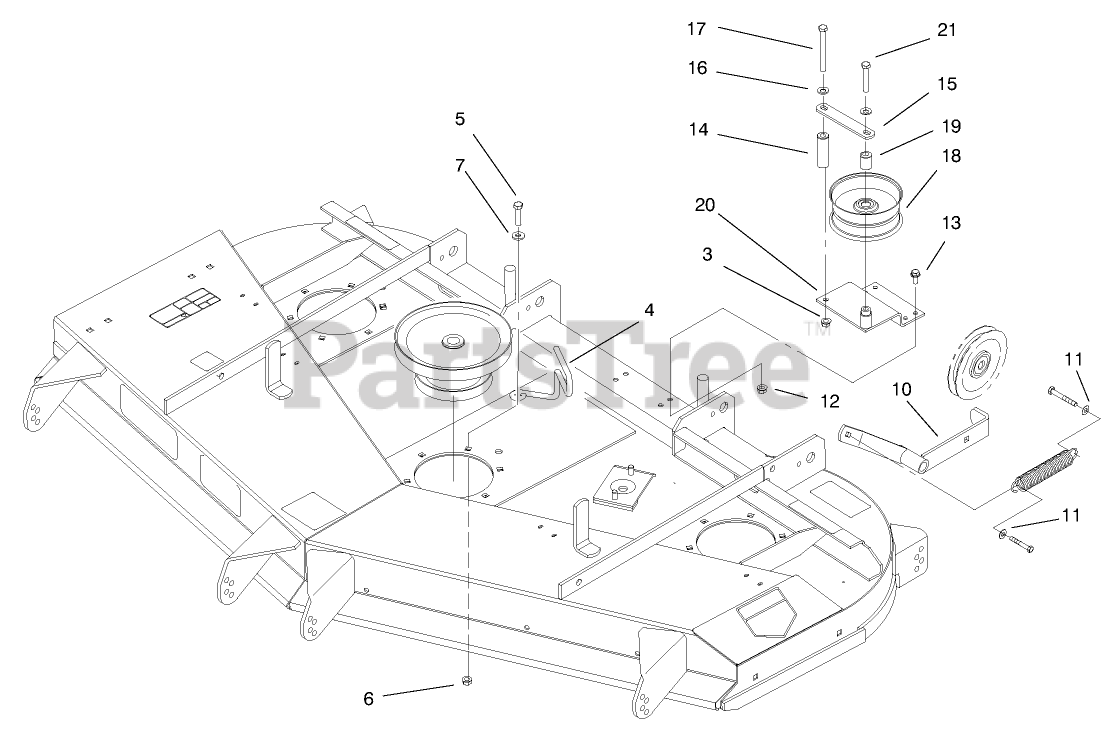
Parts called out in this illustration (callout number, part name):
3	NUT-HHF, WHIZ
4	BELT-GUIDE
5	SCREW-HH
6	NUT-HF
7	WASHER-FLAT
10	IDLER ARM ASM
11	WASHER-FLAT
12	NUT-HF
13	SCREW-HHF
14	SPACER-BRACKET
15	Plate-Guide Belt
16	Washer
17	SCREW-HH
18	Pulley
19	Spacer
20	BRACKET-PULLEY
21	SCREW-HH
